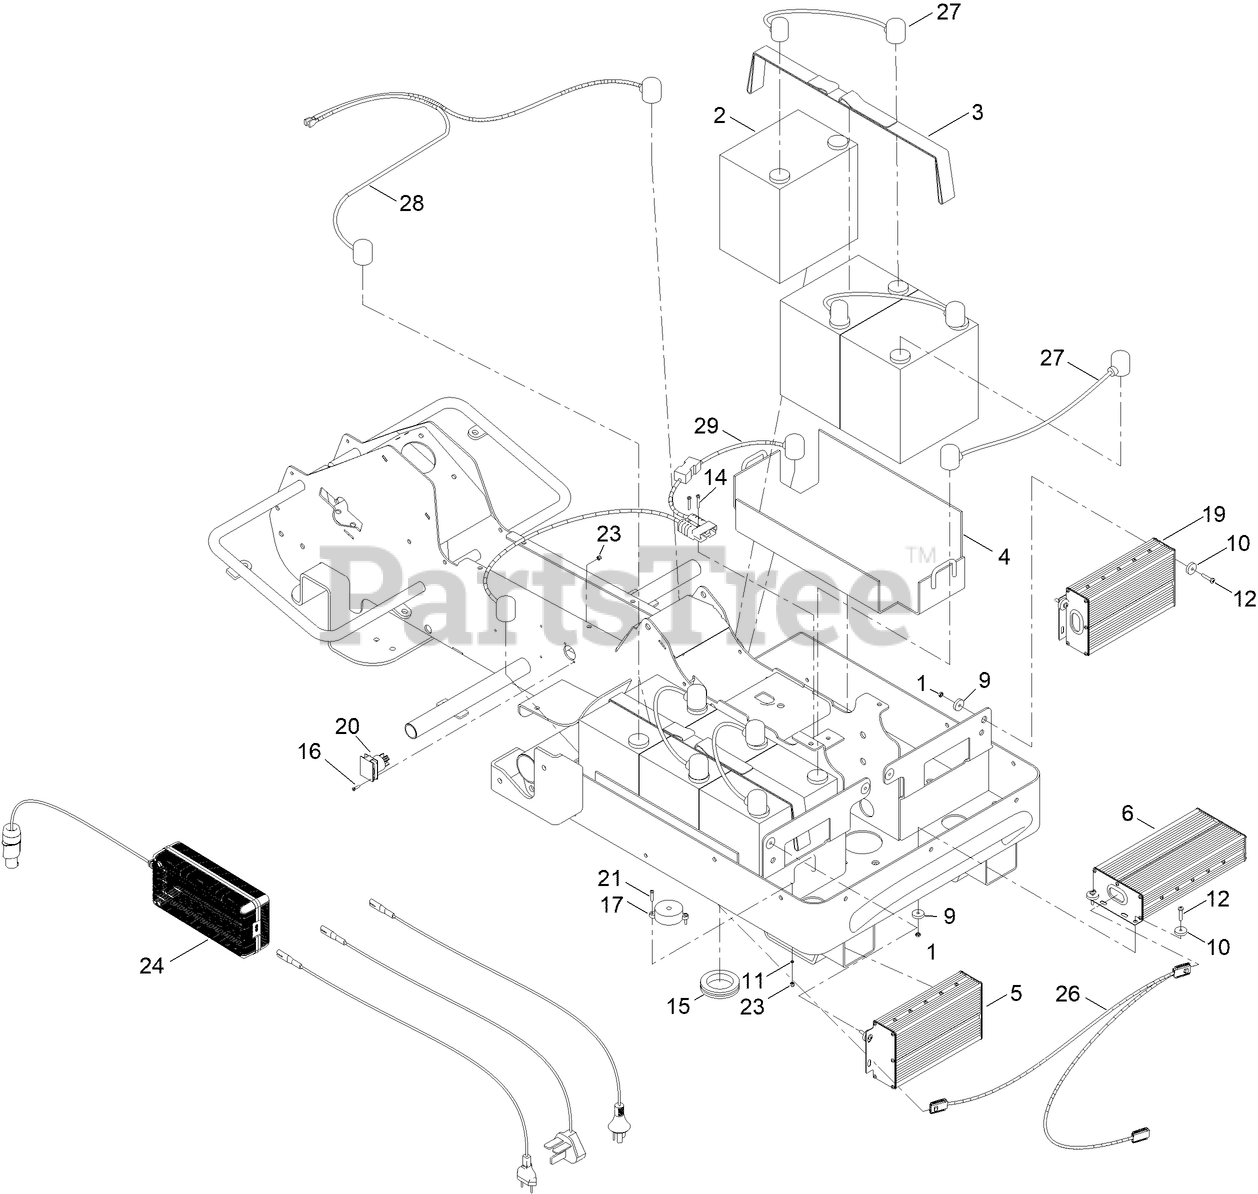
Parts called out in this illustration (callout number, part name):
2	BATTERY
3	STAP, BATTERY
4	HOLDER, BATTERY
5	CUTTING CONTROLLER
6	DRIVING CONTROLLER
9	FLAT BUSH, RUBBER
10	BUSH, RUBBER
11	SPRING WASHER
15	INSERT, RUBBER CABLE LARGE
19	CUTTING CONTROLLER
20	POWER CONNECTOR ASM
23	NUT-NYLOC
24	CHARGER
26	WIRING HARNESS, CONTROLER CONNECTOR
27	WIRING HARNESS, BATTERY CONNECTOR
28	WIRING HARNESS, BATTERY/CHARGING WIRE
29	WIRING HARNESS, FUSE WIRE
